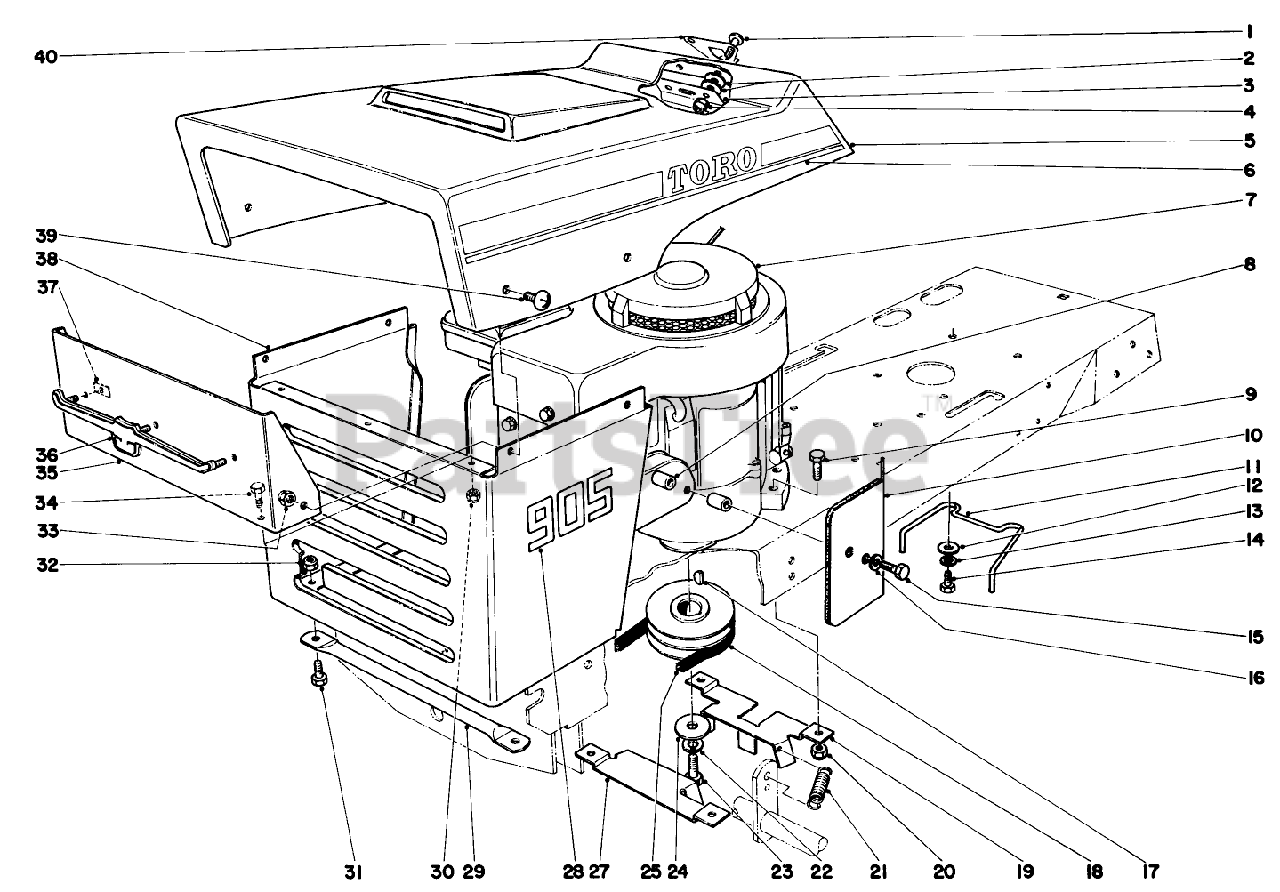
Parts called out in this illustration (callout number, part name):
2	WASHER-FLAT
3	Hood Latch
6	Decal Hood 905
7	Engine
9	SCREW-HH
11	Belt Retainer
12	WASHER-PLAIN
13	WASHER-LOCK/SP
14	SCREW-HH
15	SCREW-HH
16	WASHER-LOCK
17	KEY-WOODRUFF
18	Engine Pulley
19	Belt Guide
21	Spring Tension
22	WASHER-LOCK
23	SCREW-HH
27	Belt Guide
28	Decal 905
29	Rod Grille Mount
31	SCREW-HH
34	SCREW-HH
35	Grille Panel
36	Bullshead
37	Tinnerman Nut
38	Grille Assembly
39	Truss Head Screw
40	Hood Clip
